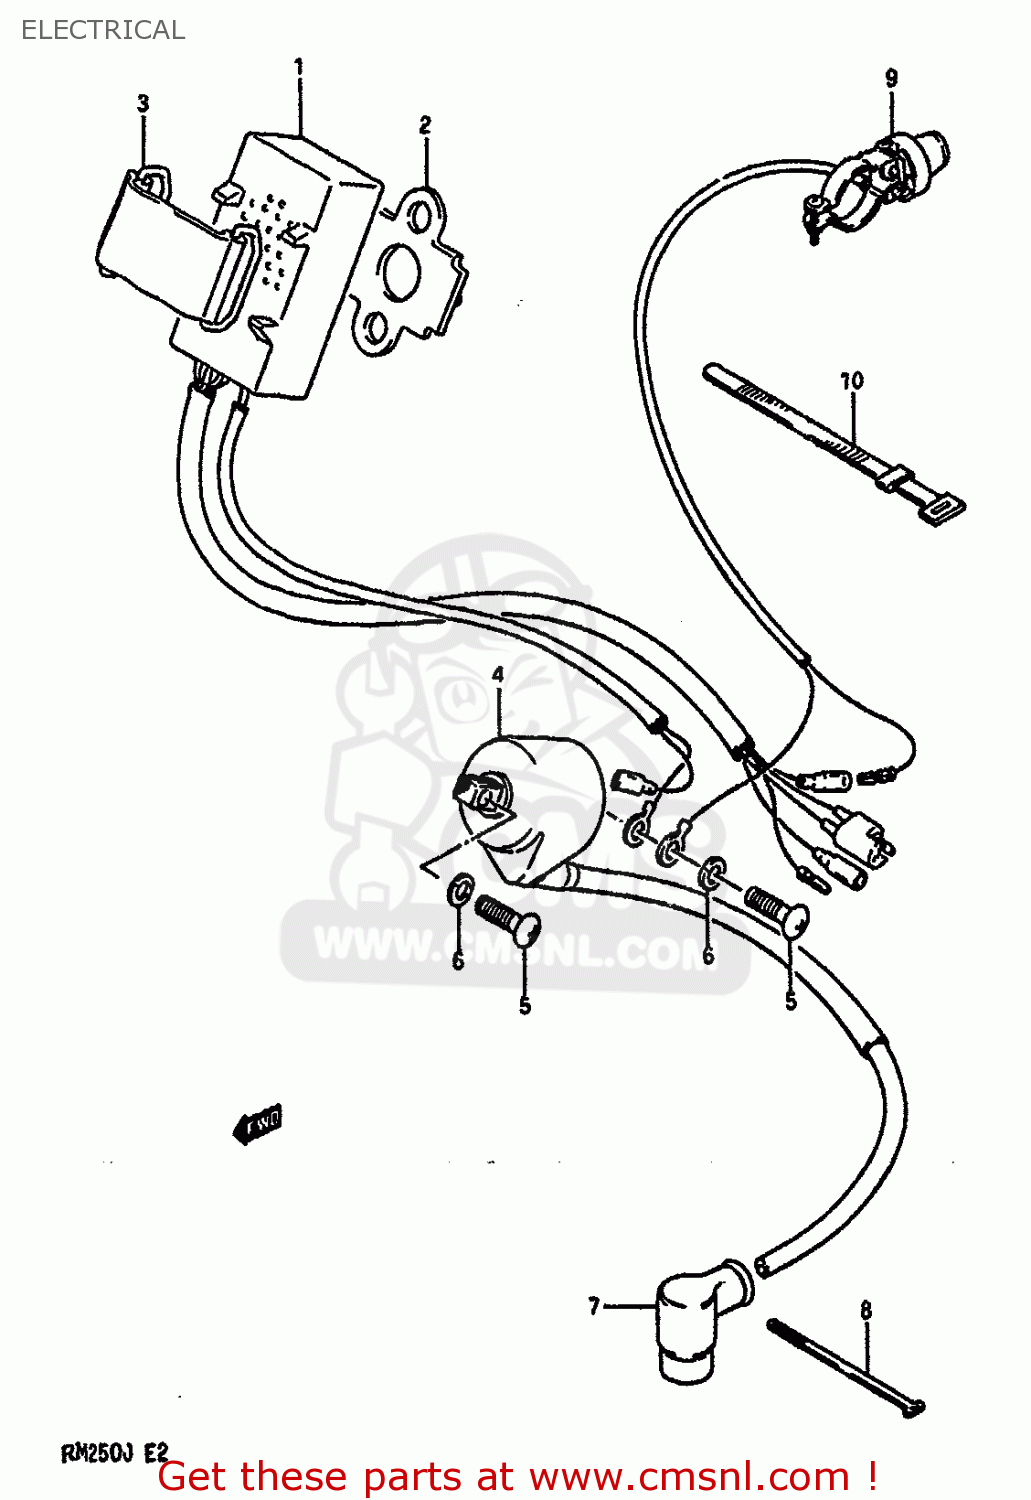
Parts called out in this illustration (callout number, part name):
1	UNIT,CDI
2	PROTECTOR,CDI UNIT
3	BAND
4	COIL ASSEMBLY,IGNITION
5	SCREW
6	WASHER,LOCK
7	CAP,SPARK PLUG
8	CLAMP
9	SWITCH ASSEMBLY
10	CLAMP(L:120)
